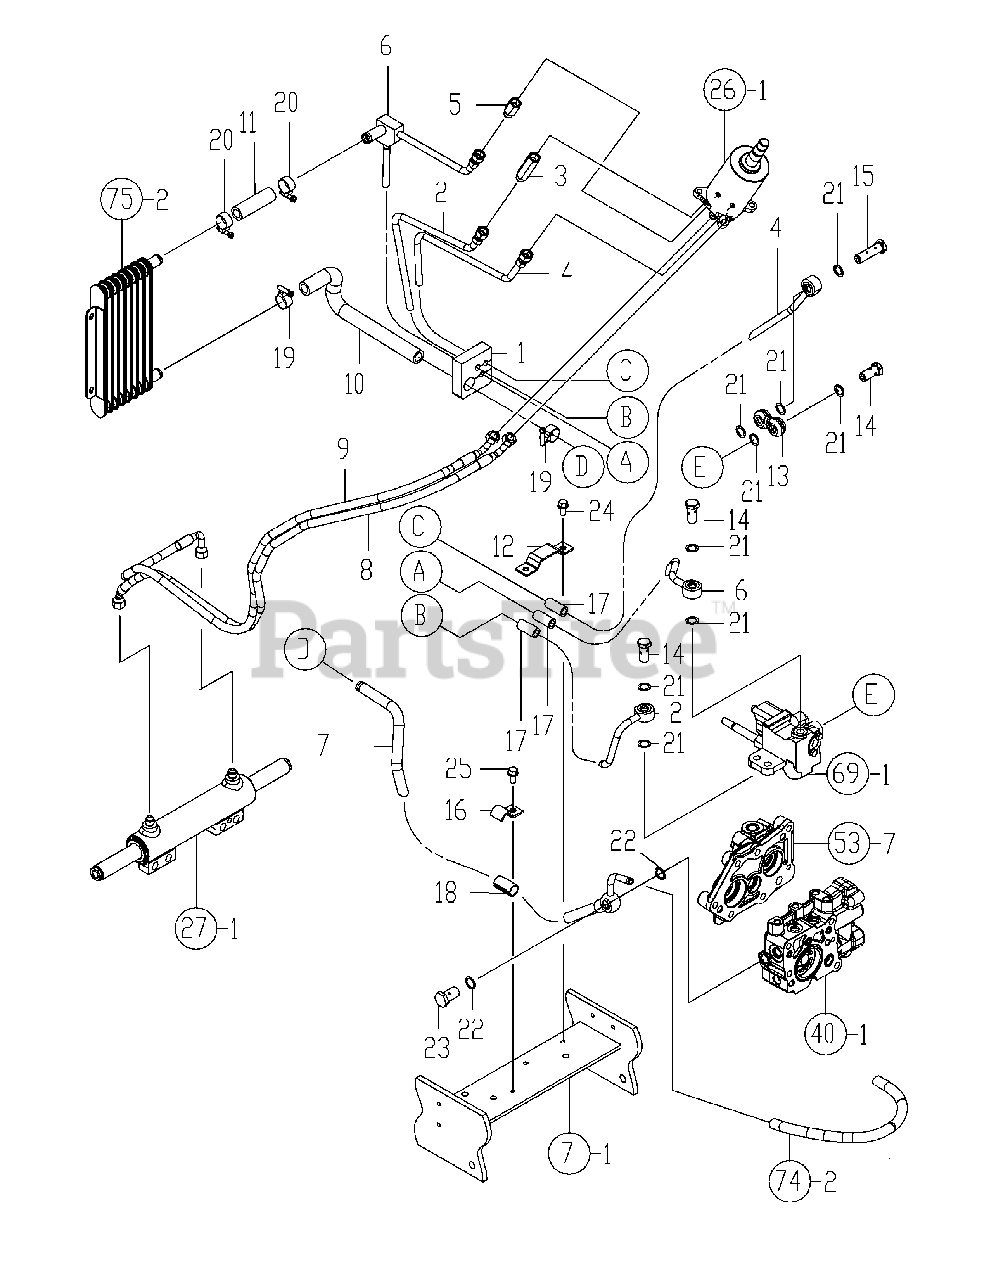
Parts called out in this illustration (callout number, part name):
2	HP PIPE, PUMP CMP
3	JOINT 9/16UNF-70
4	HP PIPE,VALVE CMP
5	JOINT 9/16UNF-40
6	LP PIPE, COOLER CMP
7	LP PIPE, TANK CMP
8	HP HOSE L, PST
9	HP HOSE R, PST
10	LP HOSE A (OIL COOLER)
11	LP HOSE B (OIL COOLER)
13	CONNECTOR 9/16UNF
14	BALL JOINT BOLT 9/16
15	BALL JOINT BOLT L 9/16
19	CLAMP, HOSE 22
20	CLAMP, HOSE 22
21	GASKET, 14 X 1.0
22	GASKET, 16 X 1.0
23	BOLT, JOINT 10
